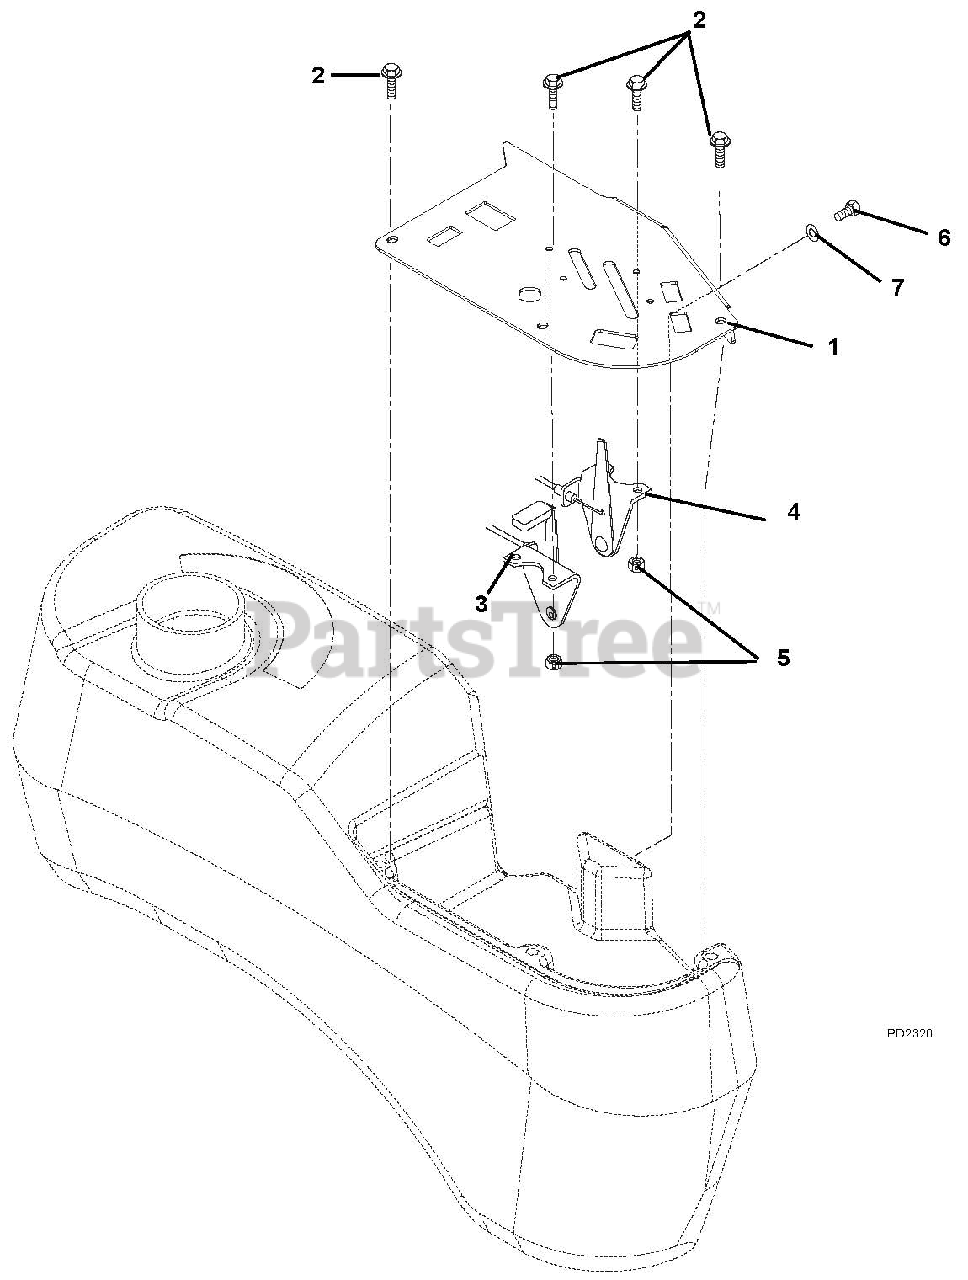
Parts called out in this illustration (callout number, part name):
1	Panel, Control
2	Screw, Machine 10-24 x .50 Hex Washer Head, Stainless
3	Throttle, Control
4	Choke Control
5	Nut, Locking Nylon 10-24 With Insert
6	Bolt, Hex .31-18 x .75 Grade 5
7	Washer, Flat-Steel .38 x .875 x .083
